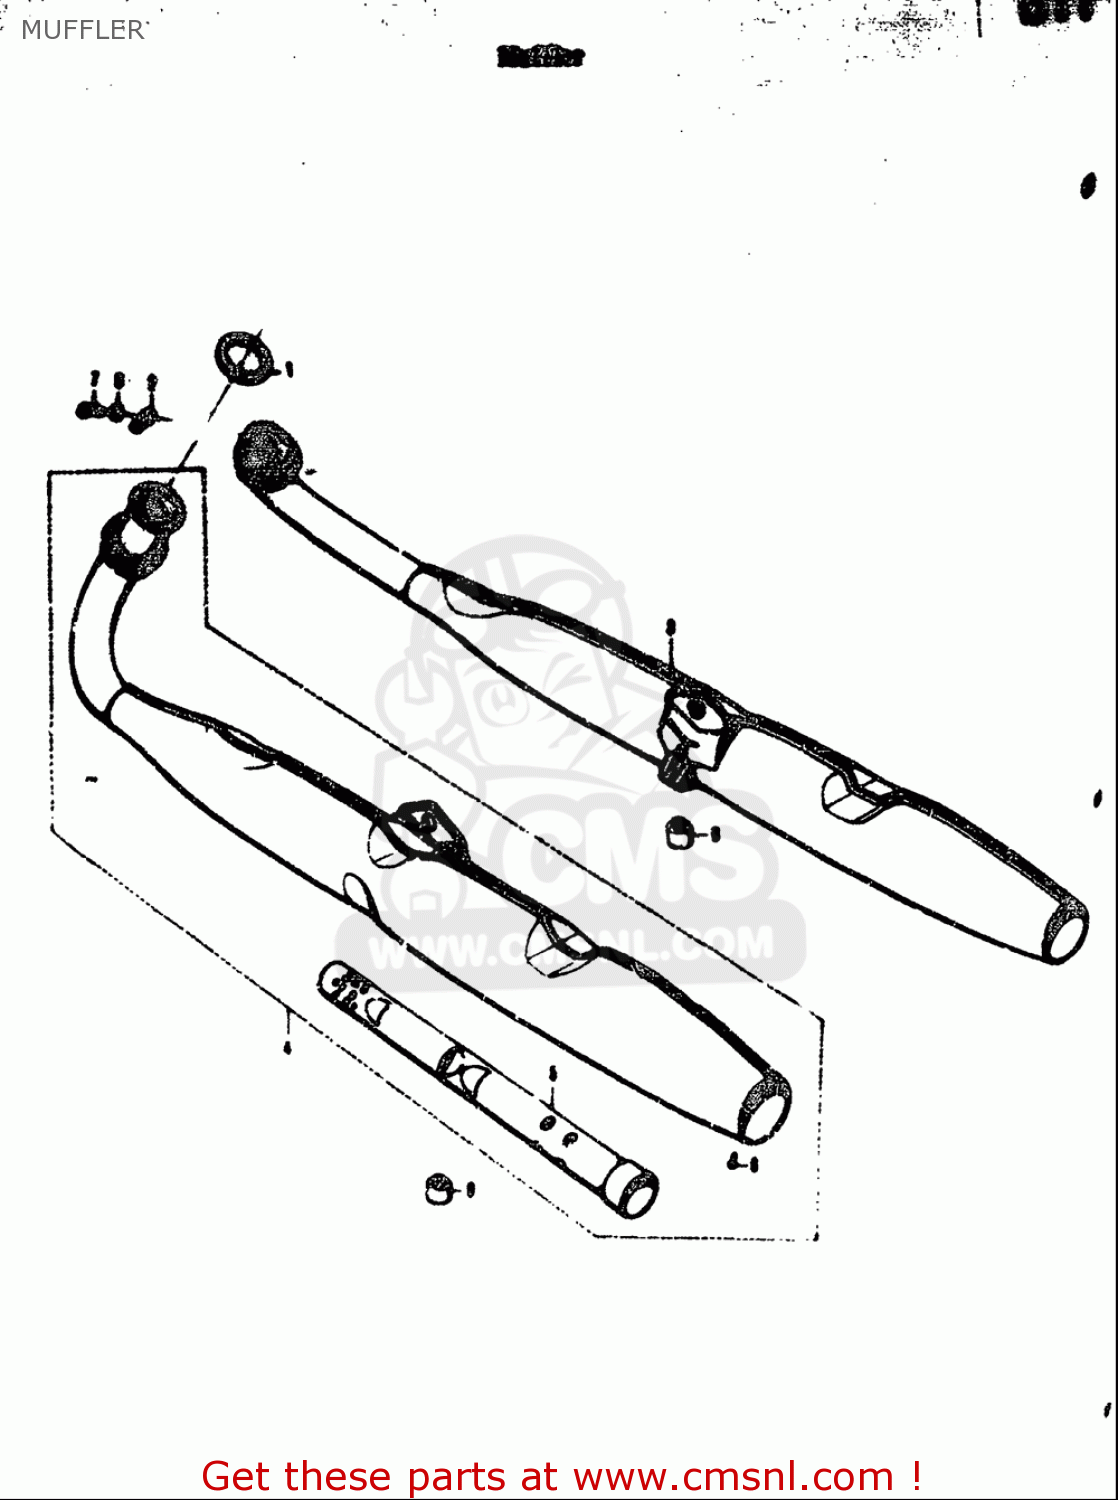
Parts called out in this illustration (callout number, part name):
1	GASKET,EXHAUST PIPE (NAS)
2	PLATE,EXHAUST PIPE
7	SCREW
8	WASHER,LOCK
9	CUSHION
